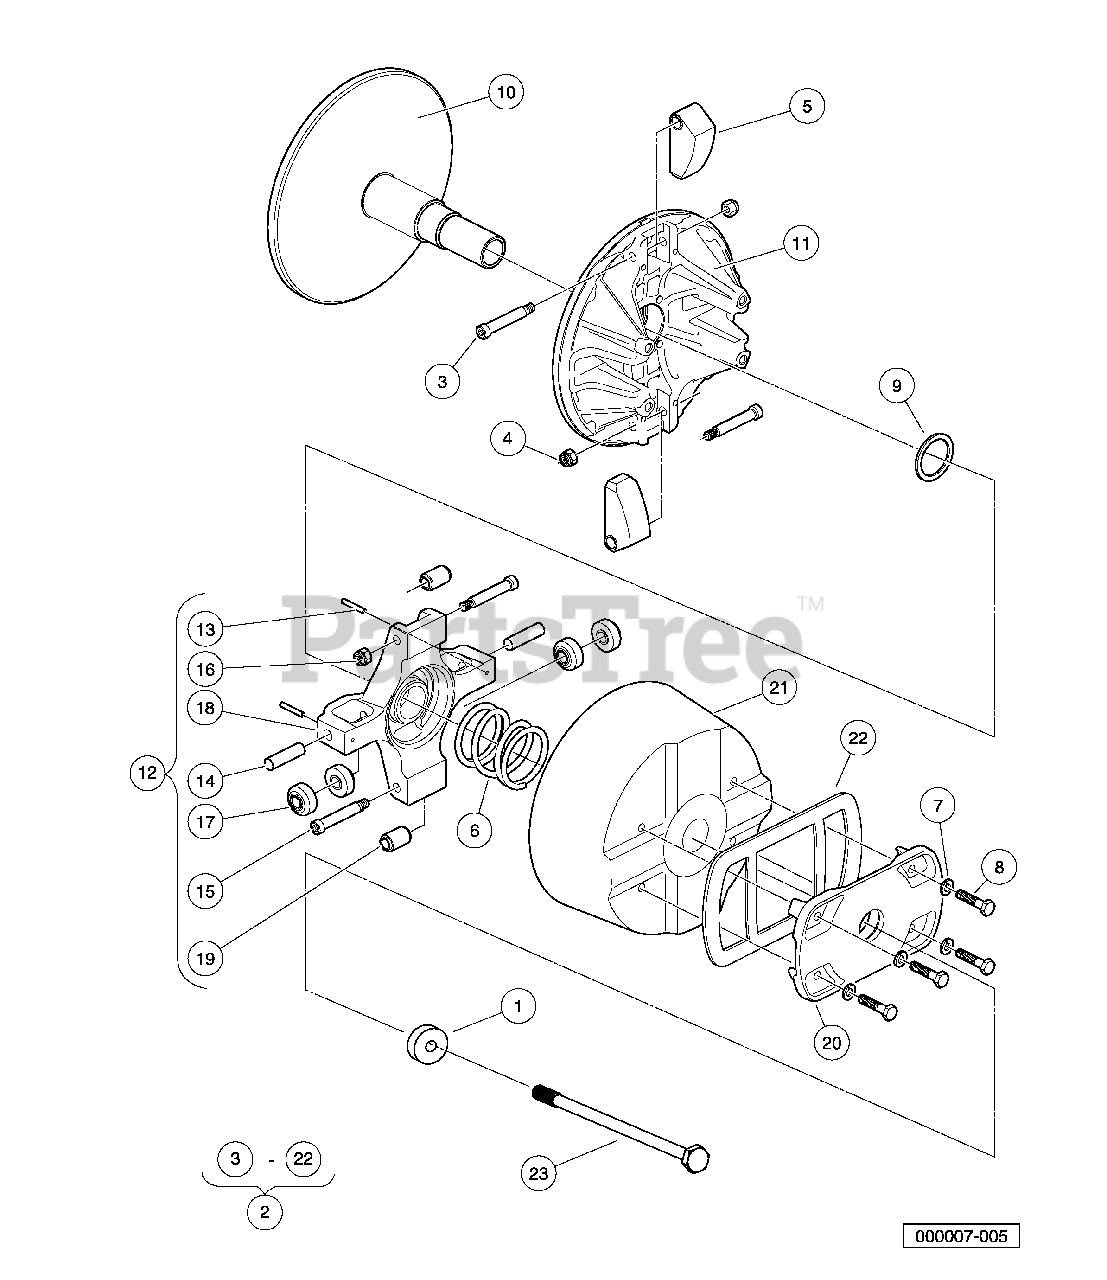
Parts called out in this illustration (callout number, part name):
1	Washer, Stepped
2	Clutch, 4x4, Gas, W/cover
3	Screw, Shlder Hex, .312 X 1.75
4	Nut, Lock Hex, 1/14-20, Flexlc
5	Sub Assy, Wt Clutch, Gas
6	Spring, Compression, Primary
7	Washer, Lock, H-Spring, 1/4
8	Screw, Cap, Hex Hd, 1/4 X 1.25
9	Shim, 1.63 X 1.33
10	Subassembly, Drive Clutch
11	Subassembly, Moveable, Drive Clutch
12	Spider Subassembly (Gasoline)
13	Pin, Spring Slotted,1.25 X 1.0
14	Pin, Dowel, .375 X 1.50
15	Screw, Shlder Hex, .312 X 1.75
16	Nut, Lock Hex, 1/14-20, Flexlc
17	Roller, Torque, Gas
18	Spider, Drive Clutch
19	Sub Assy, Roller Weight
20	Cover, Drive Clutch
21	Cover, Clutch, 4x4
22	Gasket, Cover, Clutch, 4x4
23	Bolt, M8 X 1.25 X 200, Loctite
